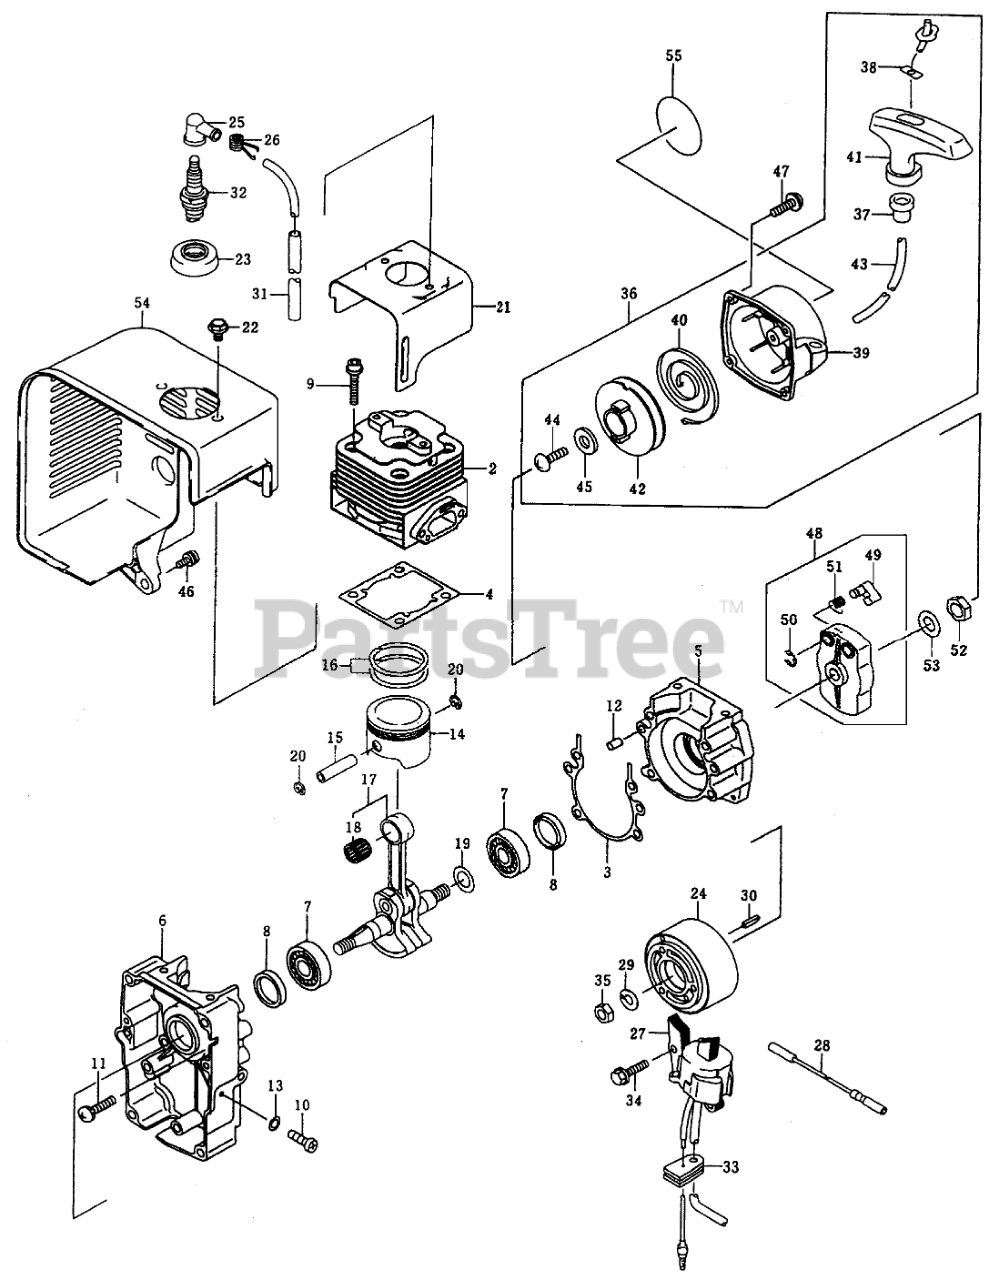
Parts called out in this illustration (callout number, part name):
1	Engine
2	CYLINDER-ENGINE
3	GASKET,CRANKCASE
4	GASKET,CYLINDER
5	CRANKCASE
6	CRANKCASE "A"
7	BEARING-BALL,6202C3
8	SEAL-OIL
10	SCREW-PAN
11	SCREW-PAN-WS-CROS
12	PIN-DOWEL
13	GASKET
14	PISTON-ENGINE
15	PIN-PISTON
16	RING SET-PISTON
17	CRANKSHAFT-ASSY
18	BEARING-NEEDLE
19	SHIM,T-0.10
20	RING-SNAP
21	SHROUD-ENGINE
24	FLYWHEEL
25	CAP-SPARK PLUG
26	TERMINAL
27	COIL-ASSY-IGNITION
28	WIRE-LEAD
29	WASHER
31	TUBE,6 X 7.4 X 300
33	GROMMET
34	BOLT-UPSET-WS
35	NUT-HEX-FINE
36	STARTER-RECOIL
37	GUIDE, ROPE
38	PLATE,RECOIL STARTER
39	CASE,RECOIL STARTER
40	SPRING,RECOIL
41	GRIP,RECOIL STARTER
42	REEL,RECOIL STARTER
43	ROPE,3.8 X 850
44	SCREW, 5 X 12
45	WASHER
46	SCREW
47	SCREW, 4 X 16
48	PULLEY-STARTING
49	PAWL,RECOIL STARTER
50	RING-SNAP
51	SPRING,RETURN
52	NUT-HEX-FINE
53	W-PLAIN-S
54	SHROUD-ENGINE
55	DECAL - ENGINE
